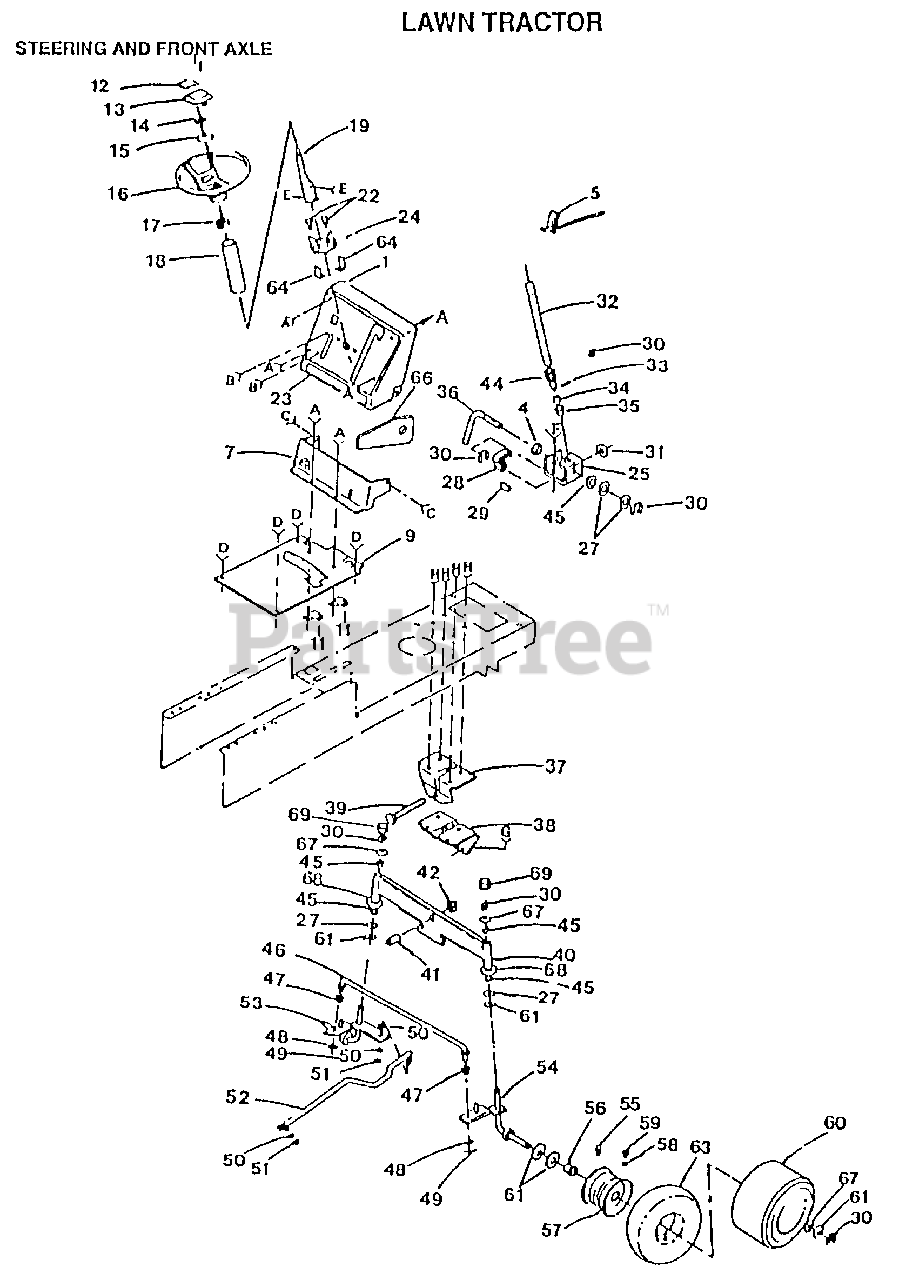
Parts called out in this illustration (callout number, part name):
4	NYLINER T
7	DASH-LOWER LT
11	CLIP T
13	INSERT-WHEEL LT
15	WASHER
17	ADAPTER LT
19	STEERING SHAFT
24	BUSHING T
27	WASHER .T
28	GEAR.SECTOR.HYT
29	KEY-WOODRUFF LT
30	RING
32	STEERING SHAFT T
34	SHAFT SPACER LT
35	BUSHING
36	ROD STEERING T
37	SUPPORT-SADDL T
38	SUPPORT.SADDLE.FT
39	BOLT LT
41	BEARING
42	"NUT-LOC,FLANGE LT"
44	GEAR PINION T
45	COL. SRTG. BEAR.
48	WASHER
49	COTTER PIN
50	LOCKWASHER
52	LINK-DRAG LT
53	SPINDLE-LH LT
55	FITTING LT
56	"FLANGE, BEARING"
58	VALVE CAP
59	VALVE STEM LT
61	WASHER
63	TUBE.5.3/4.5/6
64	RETAINER T
67	WASHER
68	WASHER
69	CAP
